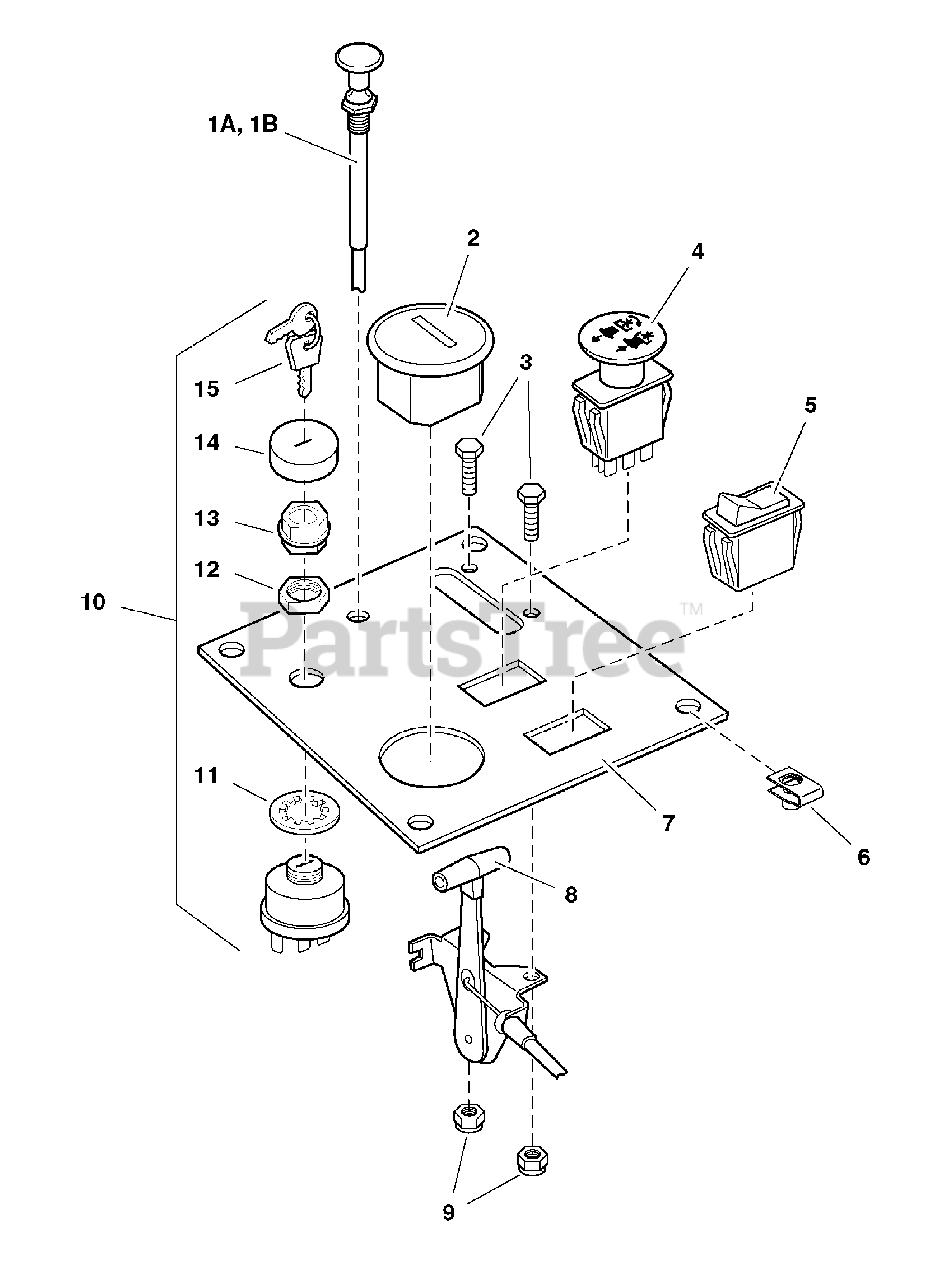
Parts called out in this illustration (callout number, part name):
1A	CABLE, Choke Control (S/N 101-540)
1B	CABLE, Choke Control (S/N 541 & up)
3	CAPSCREW, Hex Hd, 1/4-20 x 3/4
4	SWITCH, PTO
5	SWITCH, Headlight
6	BODY CLIP, 5/16-18
7	INSTRUMENT PANEL
8	CABLE, Throttle Control
9	NUT, Hex, Nylon Lock, 1/4-20
10	SWITCH, Ignition, Complete (Includes Ref 11-15)
12	STEEL NUT
13	PLASTIC NUT
15	KEY, Ignition, Molded (set of 2)
